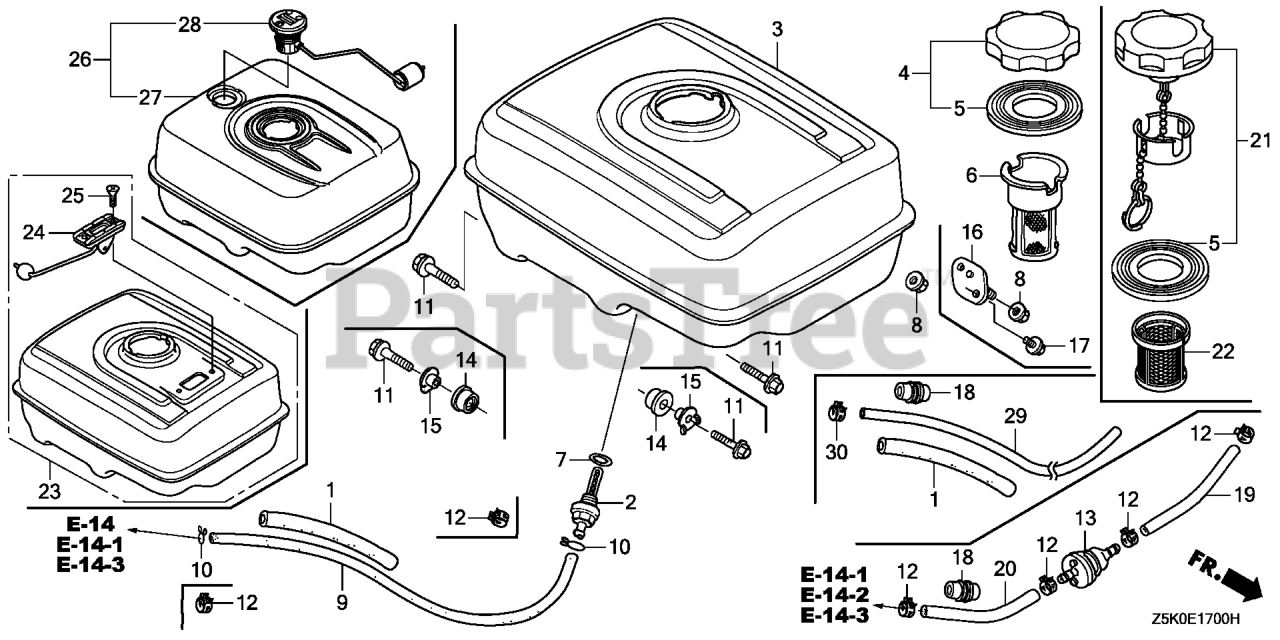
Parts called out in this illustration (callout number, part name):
1	RUBBER, SUPPORTER (107MM)
2	JOINT, FUEL TANK
5	GASKET, FUEL FILLER CAP
5	GASKET, FUEL FILLER CAP (39X62X3) (TOUYOUSYA)
7	O-RING (14MM) (ARAI) Use up to Engine SN 2949254.
8	NUT, FLANGE (8MM)
9	TUBE, FUEL (4.5X210) (FKM)
11	BOLT, FLANGE (8X25)
12	CLIP, TUBE (D8)
21	CAP, FUEL FILLER
22	FILTER, FUEL (FROM 1204807)
27	TANK, FUEL *NH1* (BLACK)
27	TANK, FUEL *NH31* (MCKINLEY WHITE)
